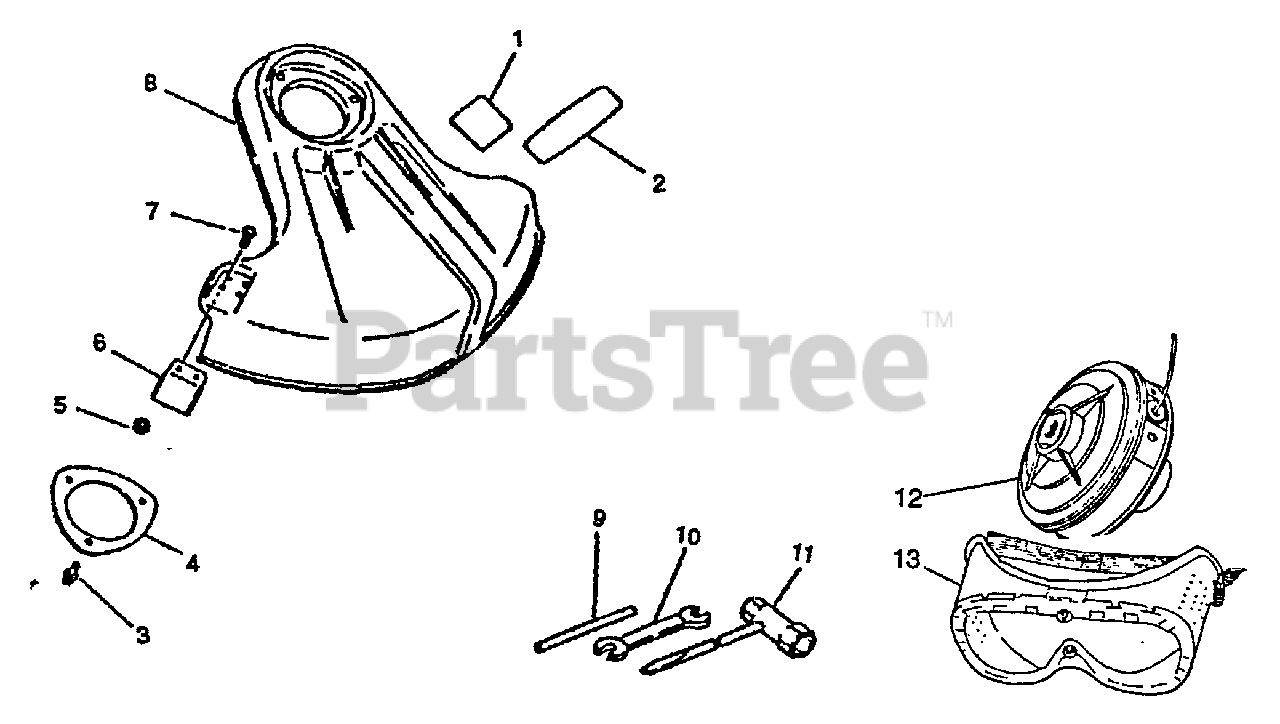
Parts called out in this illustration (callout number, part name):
1	LABEL, CAUTION
2	LABEL, ECHO
3	SCREW 5×16
4	BRACKET, SHIELD
5	NUT M5
6	CUTTER, LINE
7	SCREW 5×16
9	TOOL, LOCKING 5×120 MM
10	SPANNER 8×10
11	T-WRENCH
12	KNIFE, TRIMMER LINE
